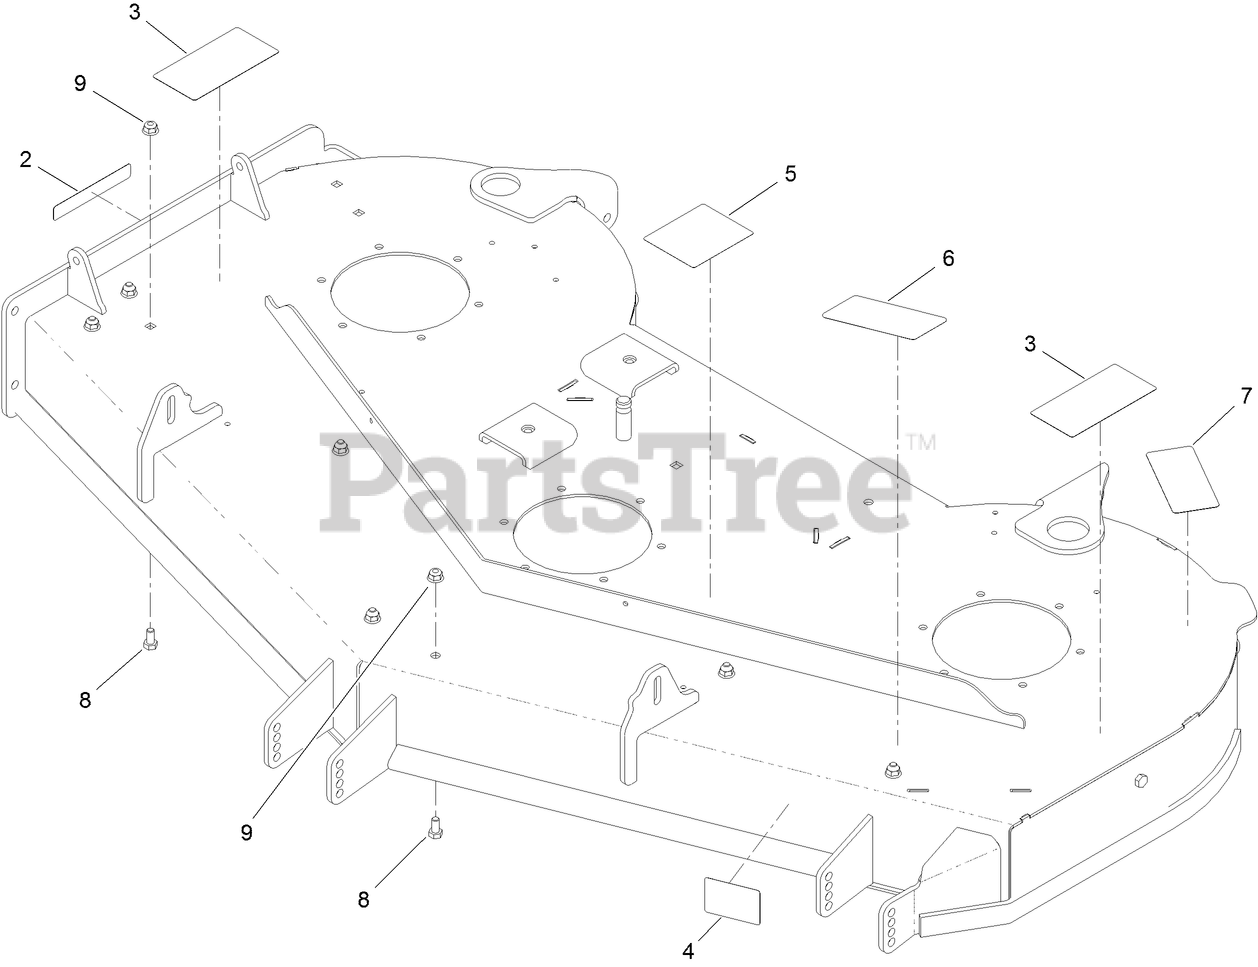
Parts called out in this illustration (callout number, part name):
2	DECAL-DANGER
3	DECAL-DANGER
4	DECAL-SCALP, ANTI
5	DECAL-ROUTING, BELT
6	DECAL-DECK, 54 INCH
7	DECAL-TORQUE, BLADE BOLT
8	SCREW-HH
9	NUT-HF, NI
